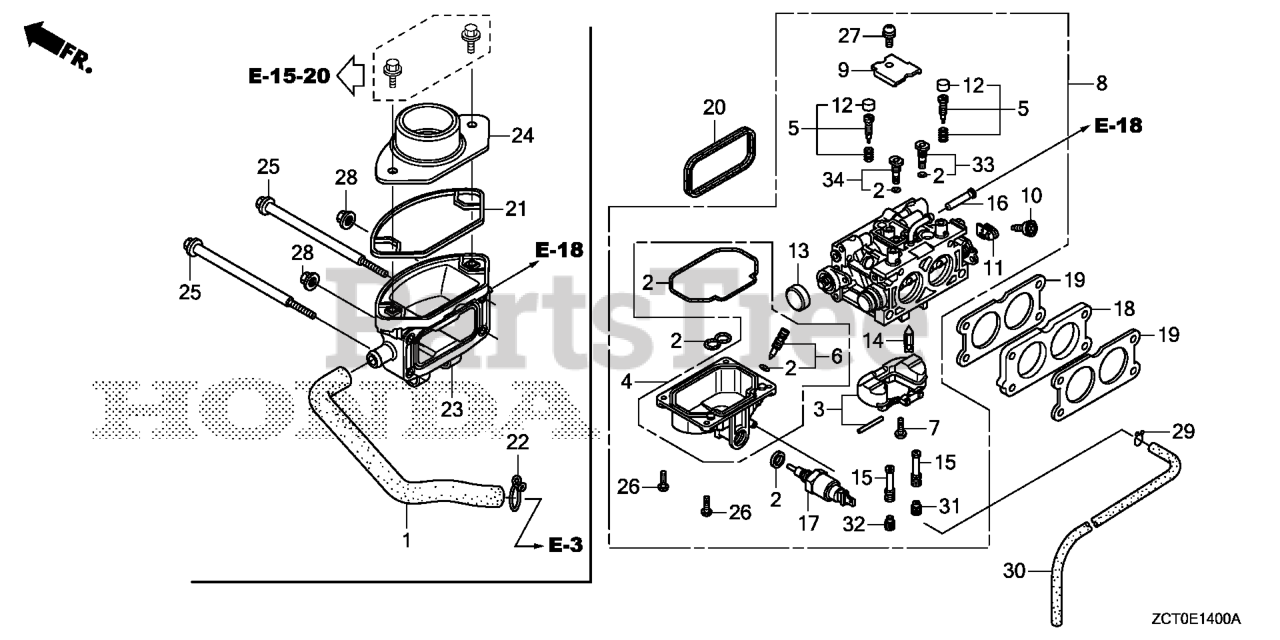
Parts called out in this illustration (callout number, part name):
1	TUBE, BREATHER
2	GASKET SET
4	CHAMBER SET, FLOAT
5	SCREW SET (CARBURETOR NO.)
6	SCREW SET, DRAIN (ADVENTURE GREEN) (CARBURETOR NO.)
7	SCREW, FLOAT
8	CARBURETOR ASSY. (BK07M B)
10	SCREW, THROTTLE STOP
11	ARM, THROTTLE LINKAGE
12	CAP, ADJUSTING SCREW (CARBURETOR NO.)
13	CAP, CHOKE LEVER DUST
14	VALVE, FLOAT
15	NOZZLE, MAIN
16	SCREEN, FUEL STRAINER
17	VALVE ASSY., SOLENOID
18	INSULATOR, CARBURETOR
19	GASKET, CARBURETOR
20	GASKET, AIR CLEANER
21	SEAL, AIR CLEANER HOUSING
22	CLIP, BREATHER TUBE
23	ELBOW, AIR CLEANER
24	JOINT, CONNECTING TUBE
25	BOLT, FLANGE (6X106)
26	SCREW, PAN (4X12)
27	SCREW-WASHER (5X10)
28	NUT, FLANGE (6MM)
29	CLIP, TUBE (B8)
30	BULK HOSE, VACUUM (4.5X1000) (4.5X450) (BULK HOSE 95005-45008-10M)
31	JET, MAIN (#92)
31	JET, MAIN (#98) Use from Engine SN BE87A A to BE87A A.
31	JET, MAIN (#105) Use from Engine SN BE87H A.
32	JET, MAIN (#92)
32	JET, MAIN (#98) Use from Engine SN BE87A A to BE87A A.
32	JET, MAIN (#105) Use from Engine SN BE87H A.
33	JET SET, PILOT (#40) (ADVENTURE GREEN) (CARBURETOR NO.)
34	JET SET, PILOT (#40) (ADVENTURE GREEN) (CARBURETOR NO.)
